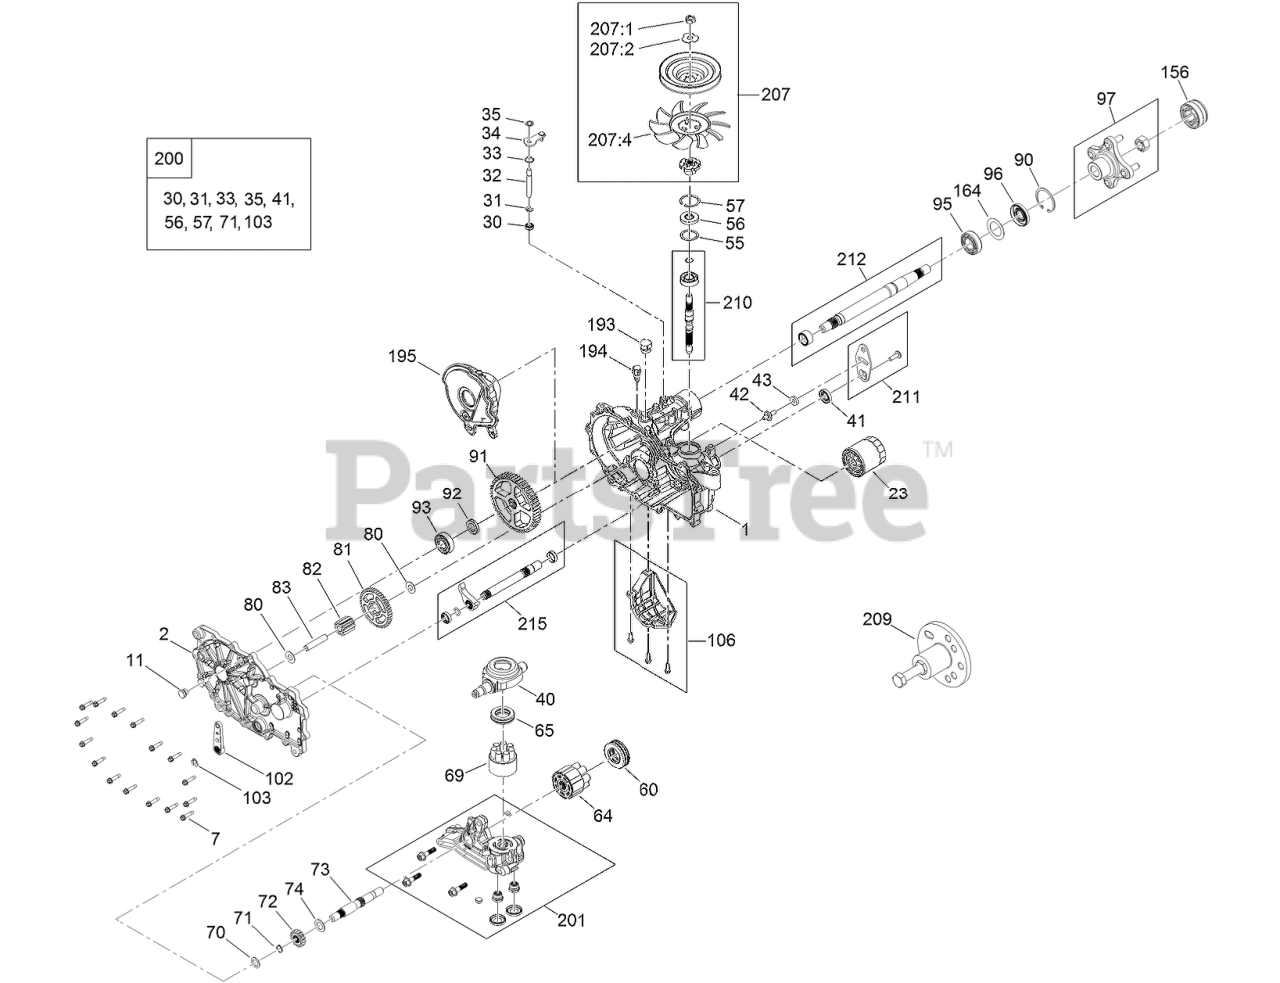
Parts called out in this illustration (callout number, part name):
1	KIT-HOUSING MAIN LH, CNTL
2	LH SIDE COVER KIT
7	SCREW-HHF
23	ELEMENT-OIL FILTER, HYD
30	SEAL-LIP
31	RING-RETAINING, EXTERNAL
32	ROD-BYPASS
33	RING-RETAINING, INTERNAL
34	ARM-BYPASS
35	RING-RETAINING, EXTERNAL
40	SWASHPLATE-TRUNNION
41	SEAL-LIP
43	PUCK-FRICTION
55	SPACER
56	SEAL-LIP
57	RING-RETAINING
60	BEARING-THRUST
64	CYLINDER BLOCK ASM KIT
65	BEARING-THRUST
69	PUMP BLOCK ASM
70	WASHER-FLAT
71	RING-RETAINING
72	GEAR-16T
73	SHAFT-MOTOR
74	WASHER
80	WASHER
81	GEAR-43T
82	GEAR-11T
83	PIN-JACKSHAFT
90	RING-RETAINING
91	GEAR-54T
92	SPACER
93	BEARING KIT
95	BEARING-BALL
97	HUB KIT
102	HANDLE-BRAKE
103	RING-RETAINING, EXT
106	FILTER GUARD KIT
156	COVER-NUT, AXLE
164	SPACER
194	BREATHER FITTING ASM
195	LH INTERNAL EXPANSION TANK ASM
200	SEAL KIT
201	CENTER SECTION KIT
207	FAN AND PULLEY KIT
207:1	NUT-HJ
207:2	WASHER-SLOTTED
207:4	FAN 7.0 X 10 BLADE
210	KIT-INPUT SHAFT
211	CONTROL ARM KIT
212	AXLE SHAFT KIT
215	INBOARD KIT
